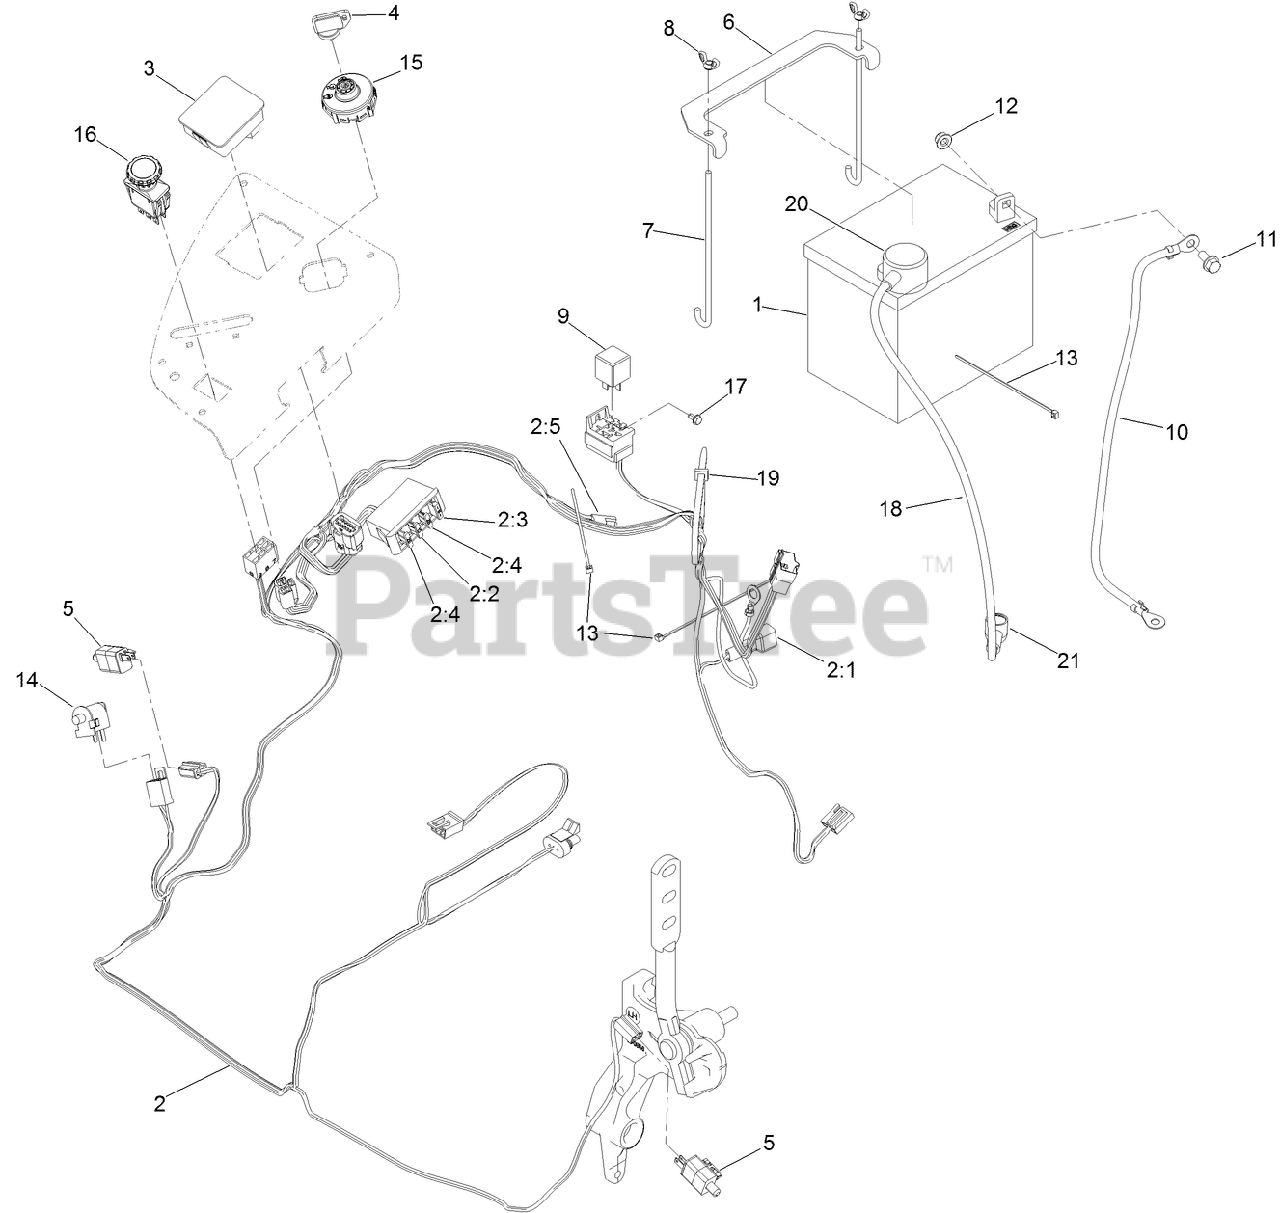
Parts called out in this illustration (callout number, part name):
1	BATTERY-DRY
2	HARNESS-WIRE, MAIN
2:2	FUSE-BLADE, 10 AMP
2:3	FUSE-BLADE, 15 AMP
2:4	FUSE-BLADE, 25 AMP
2:5	CAP-PLUG
3	FUEL/HOUR METER ASM
4	KEYS-IGNITION (SPARE PAIR)
4	KEY-IGNITION
5	SWITCH
6	STRAP-TIE DOWN, BATTERY
7	BOLT-HOLDDOWN
8	WINGNUT
10	CABLE-BATTERY, NEGATIVE
11	SCREW-HH
12	NUT-HF, NI
13	TIE-CABLE
14	SWITCH-BAIL
15	SWITCH-IGNITION
16	SWITCH-PTO, 10 AMP
17	SCREW-HWH
18	CABLE-BATTERY, POSITIVE
19	TIE-PLASTIC
20	INSULATOR-BATTERY
21	INSULATOR-SOLENOID
